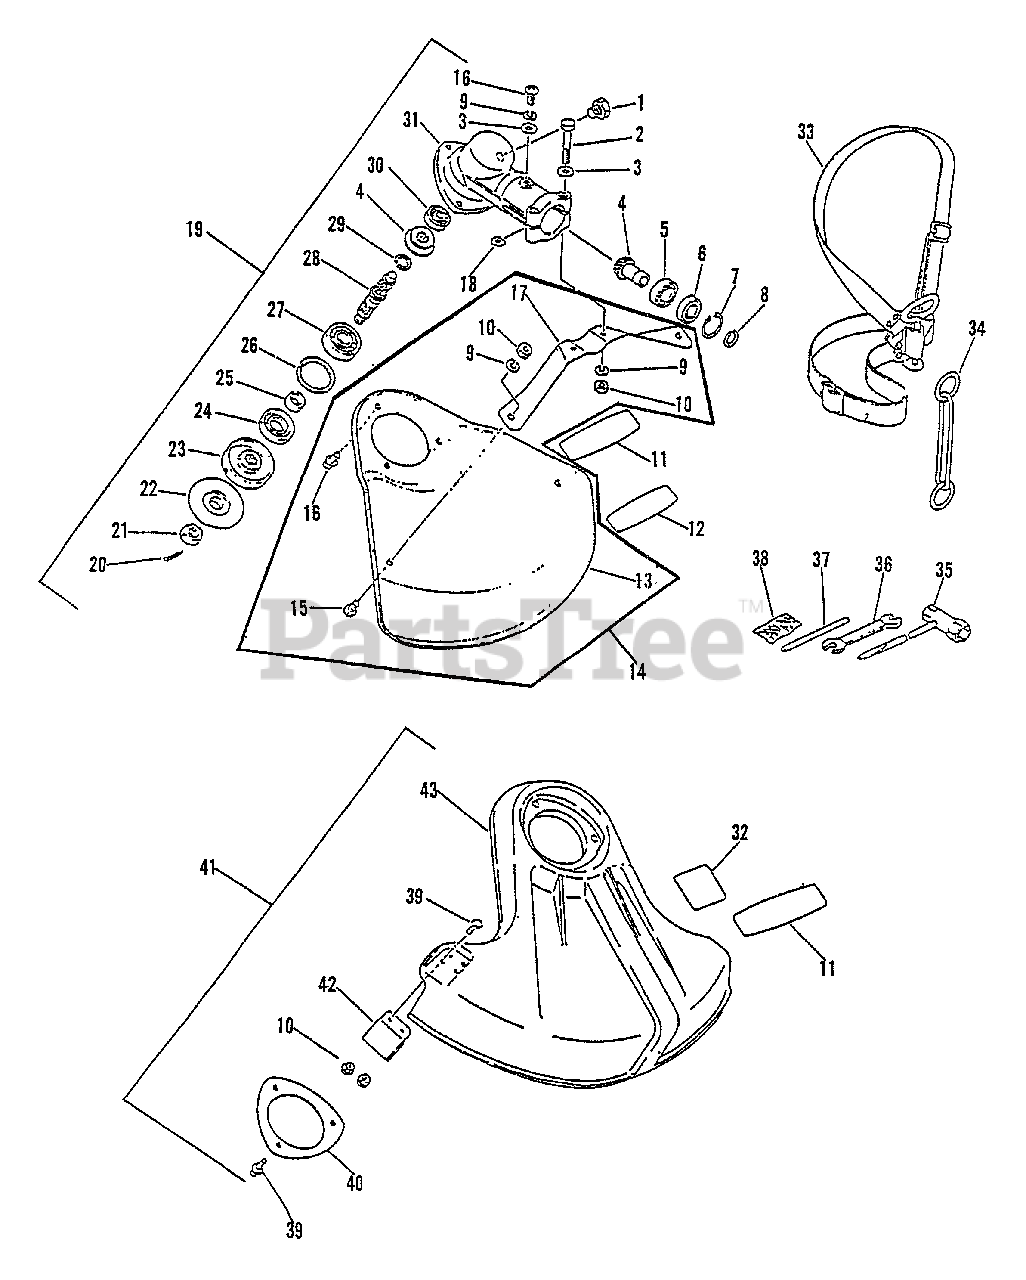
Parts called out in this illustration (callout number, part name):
1	BOLT 8×8 SP
2	BOLT 5×35 SP
3	WASHER, FLAT 5.5×10×0.8
4	GEAR SET
5	BEARING, BALL 6900
6	BEARING, BALL 6900Z
7	RING, SNAP Ø22
8	RING, SNAP Ø12
9	WASHER, SPRING 5
10	NUT M5
11	LABEL
12	LABEL - CAUTION
13	SHIELD, METAL DEBRIS
14	SHIELD ASSY
15	SCREW 5×8
16	SCREW 5×10
17	BRACKET, SHIELD MOUNTING
19	GEAR CASE ASSY
20	PIN, COTTER 2×22
22	PLATE, ADAPTOR - LOWER
23	PLATE, ADAPTER - UPPER
24	SEAL, OIL 22
25	SPACER 11.8×15×9
26	RING, SNAP Ø32
27	BEARING, BALL - 6201 C3
28	SHAFT, GEAR
29	RING, SNAP Ø10
30	BEARING, BALL 609
31	HOUSING, GEAR CASE
32	LABEL, CAUTION
33	SHOULDER STRAP ASSY
34	HOOK
35	T-WRENCH 17x-19 L200
36	SPANNER 8×10
37	TOOL, LOCKING 5×120 MM
38	PIN, COTTER 2×22 (PKG. OF 10)
39	SCREW 5×16
40	PLATE, SHIELD Ø49.5 MM
41	DEBRIS SHIELD ASSY
42	CUTTER, LINE
43	SHIELD, DEBRIS
